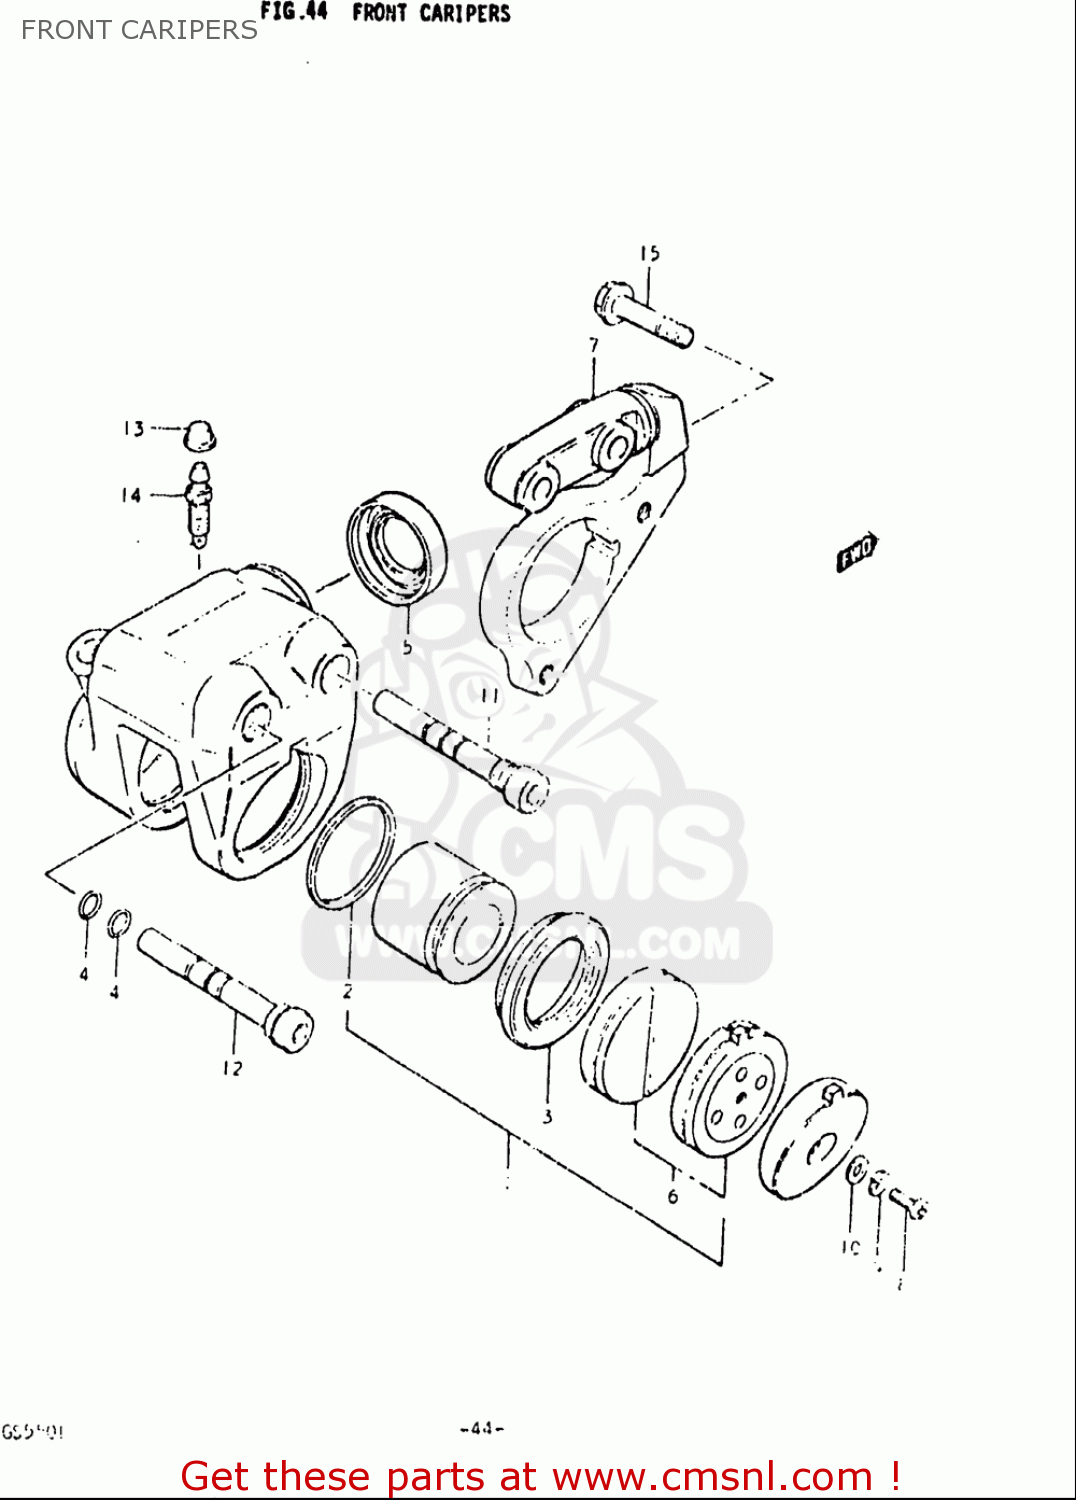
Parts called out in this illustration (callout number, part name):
2	SEAL,PISTON
4	O RING,AXLE CALIPER
5	BOOT,HOLDER
6	PAD SET (NAS)
8	SCREW
9	WASHER,LOCK
10	WASHER
11	AXLE,CALIPER
12	AXLE NO.2
13	CAP,BLEEDER PLUG
14	BREATHER
15	BOLT
